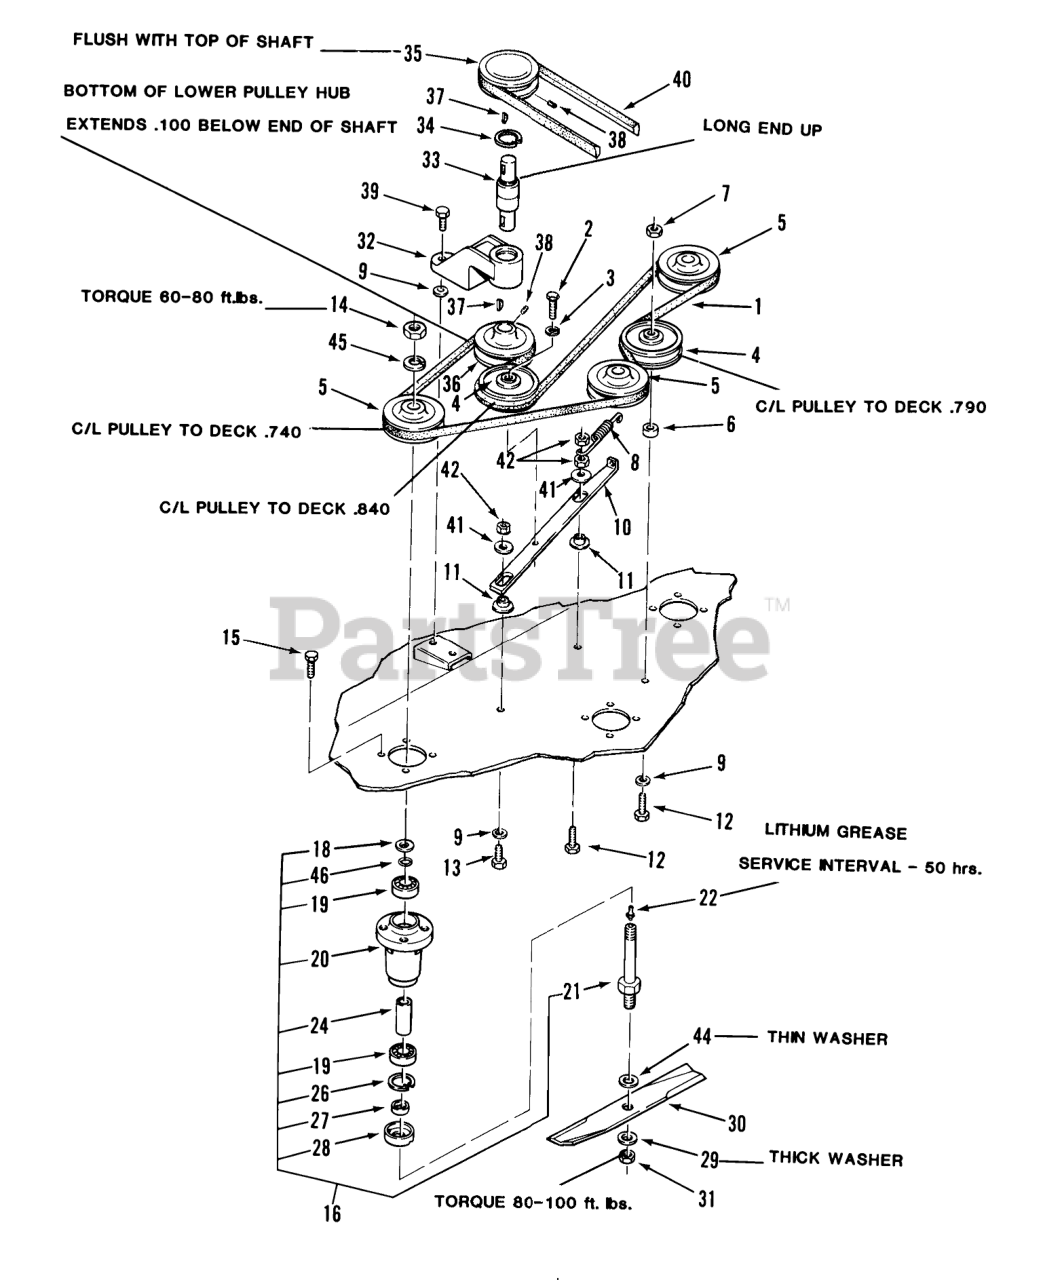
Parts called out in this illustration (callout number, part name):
1	BELT-V
2	BOLT HEX SPECIAL
3	LOCKWASHER
4	Idler Pulley
5	PULLEY
6	SPACER
7	Nut
8	SPRING-EXTENSION
9	WASHER
10	BAR-IDLER SUPPORT
11	SPACER-BUSHING
12	Bolt
13	Bolt
14	Jam Nut
15	Bolt
16	ASSY 36" SPINDLE
18	Washer
19	BEARING-BALL
20	HOUSING-SPINDLE
21	Spindle Shaft
22	Zerk
24	Spacer
26	Ring-Snap
27	SPACER-BLADE
28	CUP-SPINDLE
29	SpeciaI Washer
30	S/A BLADE KIT
31	Nut-Jam
32	HOUSING DRIVE BRG R
33	BEARING-INT SHAFT
34	Snap Ring
35	PULLEY
36	PULLEY-SPLIT
37	KEY-WOODRUFF
38	Set Screw
39	Bolt
40	V-BELT
41	WASHER
42	NUT
44	Washer
45	Lockwasher
46	O RING
